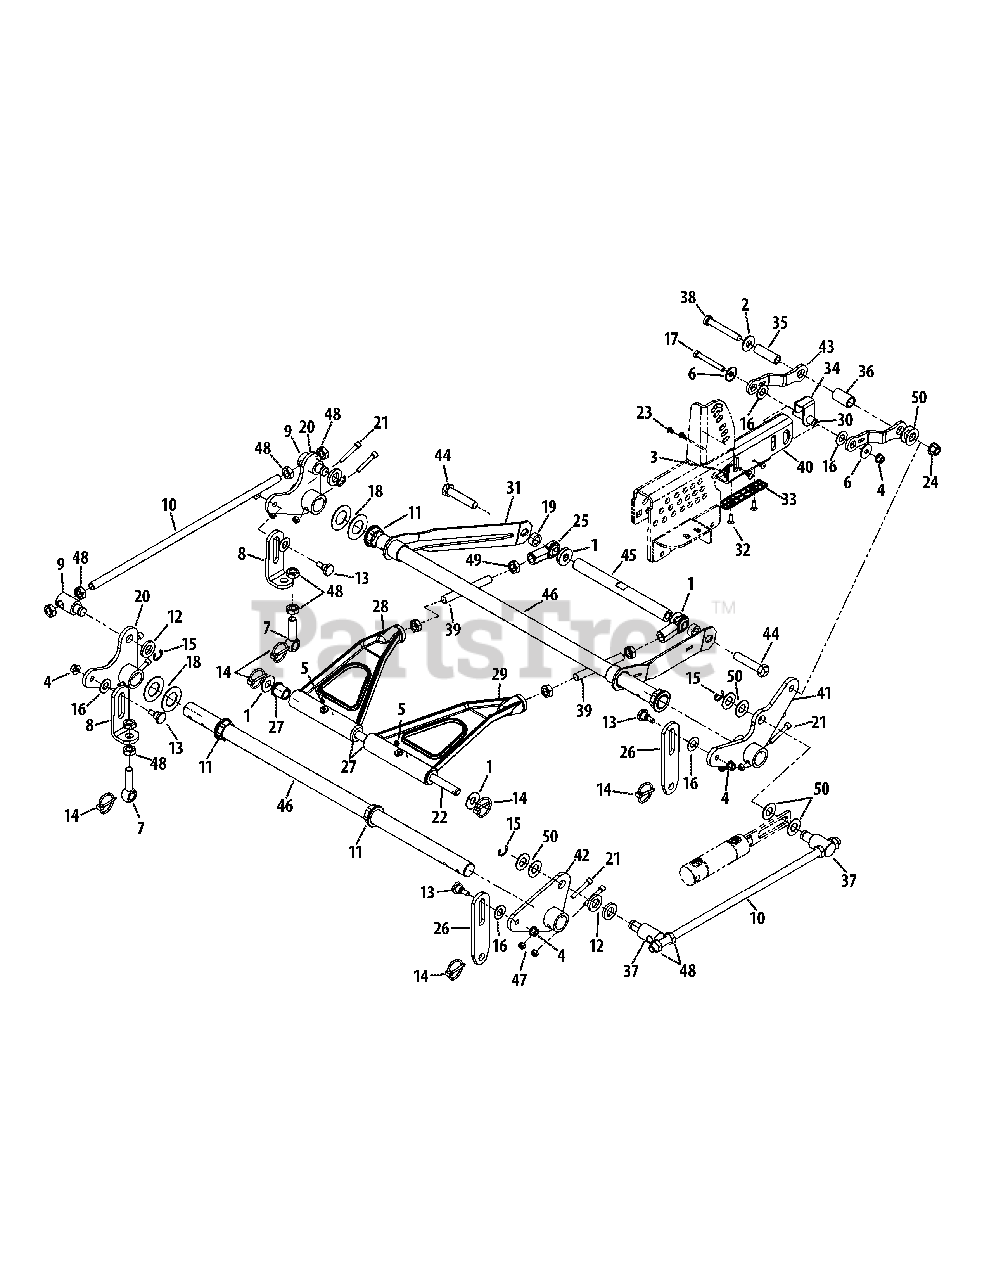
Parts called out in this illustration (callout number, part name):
1	Washer, .655 x 1.5 x .055
2	Washer, .563 x 1.38 x .109
3	Nut, 1/4-20
4	Flg. Cnter. Lock Nut, 3/8-16 (60" Deck)
4	Flange Lock Nut, 3/8-16 (72" Deck)
5	Grease Fitting, 1/4-28
6	Washer, .411 x 1.25 x 1.00
7	Eye Bolt, 5/8-16 x 2.63
8	Eye Bolt Link, 5/8
9	Lift Ferrule
10	Lift Connecting Rod
11	Hex Flange Bearing
12	Spacer, .812 x 1.47 x .218
13	Shoulder Bolt, 3/8-16 x .625 x .437
14	Lynch Pin, 3/16 x 1.25
15	Retainer Clip
16	Washer
17	Hex Screw, 3/8-16 x 3.00
18	Washer, 1.25 x 2.25 x .075
19	Spacer, .630 x 1.06 x .440
20	Assembly Bellcrank
21	Screw, 5/16-18 x 2.0
22	Deck Lift Link Rod (60" Deck)
22	Deck Lift Link Rod (72" Deck)
23	Rivet, 1/4 x .625
24	Flange Top Lock Nut, 1/2-13
25	RH Rod End, 5/8
26	Deck Lift Link
27	Flange Bearing
28	LH Lift Brace Bearing
29	RH Lift Brace Bearing
30	Spacer, .375 x .625 x 2.20
31	Front Frame Support Assembly
32	Flat Head Screw, 1/4-20 x .750
33	Wear Plate, 1.125 x 5.0
35	Spacer, .510 x .750 x 2.38
36	Spacer, .765 x 1.00 x 1.70
37	Lift Ferrule, 1.938
38	Hex Screw, 1/2-13 x 3.5
39	Rod, 5/8-18 x 5.5 (60" Deck)
39	Rod, 5/8-18 x 3.5 (72" Deck)
40	Tube, 3.0 x 1.5
41	Hydro Assist Bellcrank
42	Lift Bellcrank Assembly
43	Loft Offset Yoke Bracket
44	Hex Screw, 5/8-11 x 3.00
45	Front Lift Link Mount Shaft
46	Deck Lift Shaft (60" Deck)
46	Deck Lift Shaft (72" Deck)
47	Hex Lock Nut, 5/16 -18
48	Jam Nut, 5/8-11
49	Jam Nut, 5/8-18
50	Flat Washer, .76 x 1.49 x .06
